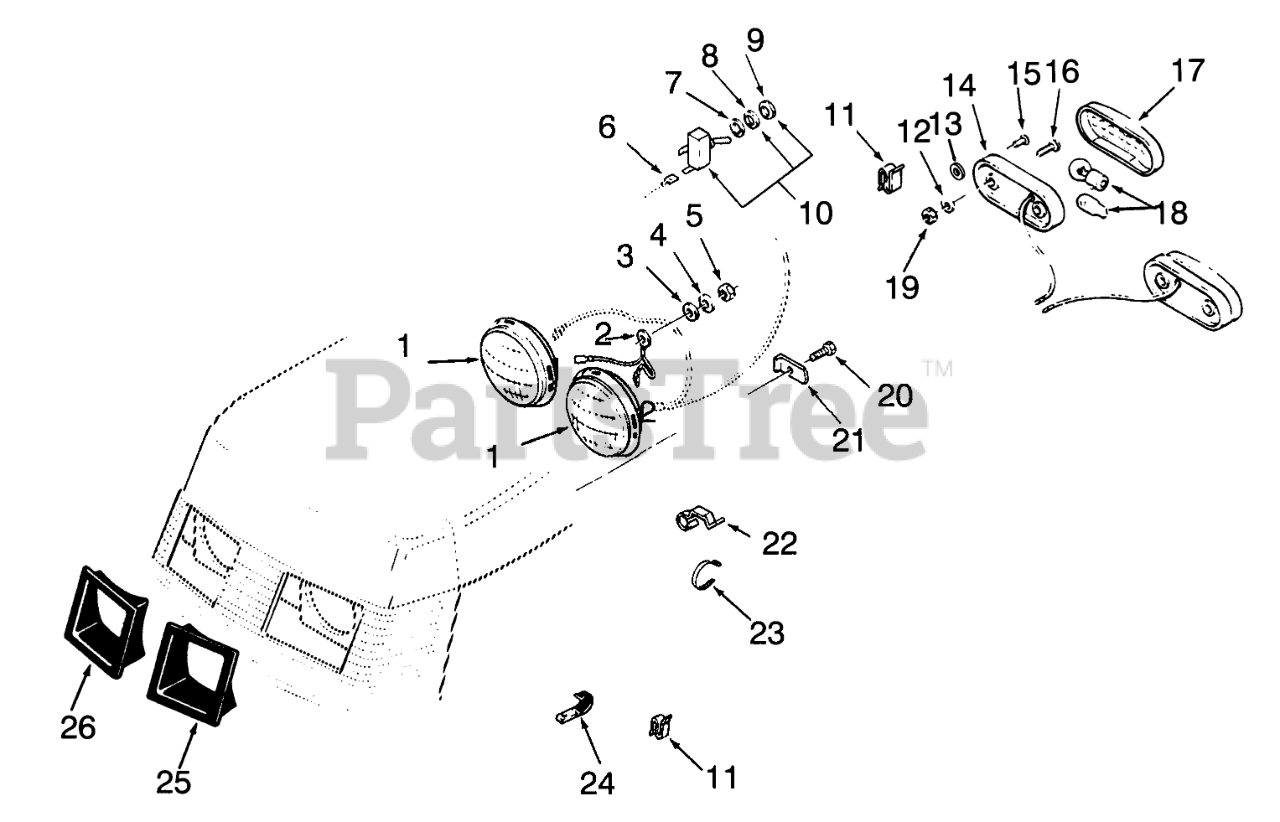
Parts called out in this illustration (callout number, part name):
1	HEADLAMP
2	LIGHT GROUND WIRE
3	WASHER-PLAIN
4	WASHER-LOCK, INTERNAL
5	NUT-LOCK, NI
6	Terminal
7	Washer
8	TAB-WASHER
10	SWITCH-LIGHTS
11	SPEED CLIP
12	WASHER-FLAT
13	WASHER-LOCK, INT
14	BASE-TAIL LIGHT
15	RIVET-POP
16	Screw
17	LENS-TAIL LIGHT
18	Bulb
19	Nut
20	Bolt
21	LOCK-HEADLIGHT
22	CLIP-WIRE
23	PLASTIC TIE
24	CLIP
25	BEZEL-HEADLIGHT, LH
26	BEZEL-HEADLIGHT, RH
